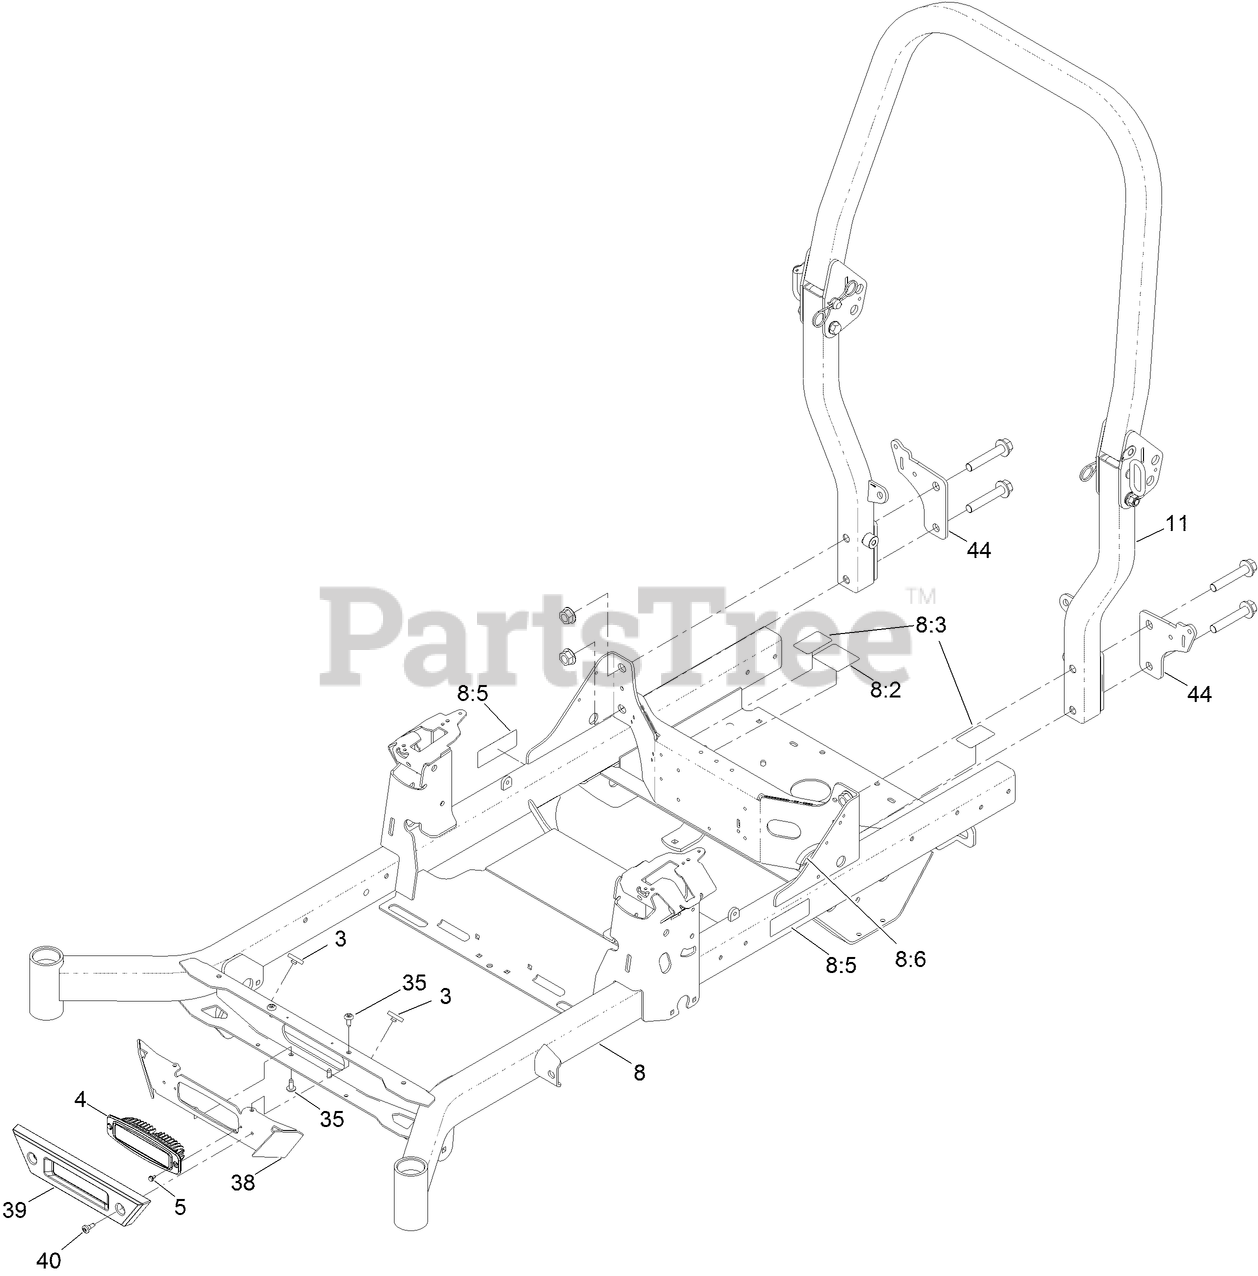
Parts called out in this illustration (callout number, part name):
3	BUMPER-PUSH-IN, RUBBER
4	MOUNT-FLUSH, LIGHT
5	SCREW-HWH
8	FRAME-60, MR
8:2	DECAL-ROUTING, BELT
8:3	DECAL-RELEASE, DRIVE
8:5	DECAL-WARNING
8:6	STRIP-SEAL
11	ASM-ROPS, MR
38	BRACKET-LIGHT [RED]
39	BUMPER-FRONT
40	SCREW-SHOULDER
